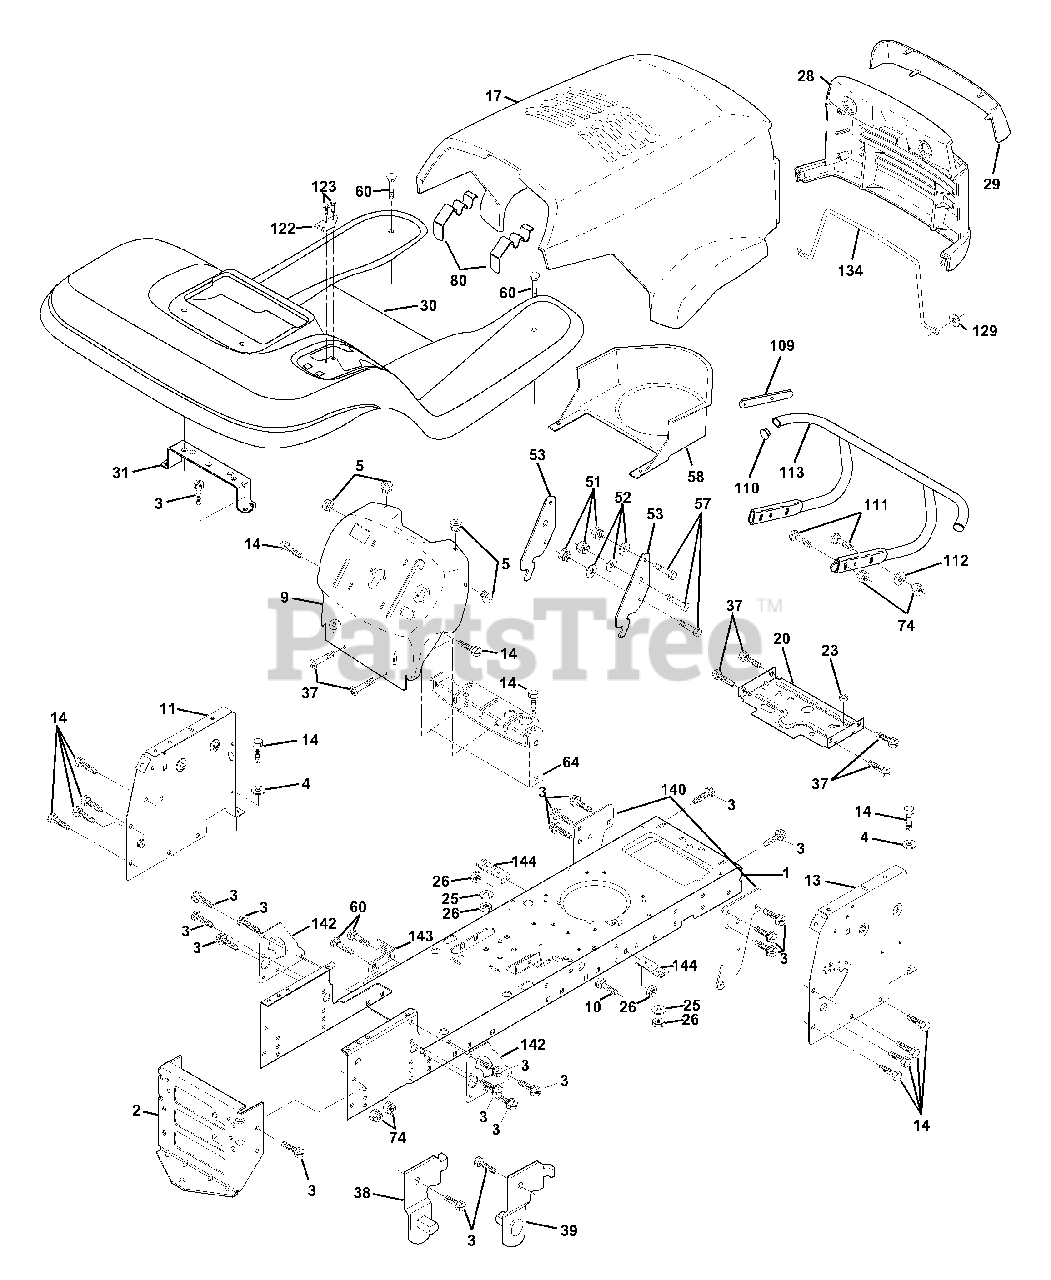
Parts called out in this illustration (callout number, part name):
1	Chassis Weldment
2	Drawbar, Stretch
3	Screw Thdrol 3/8-16x3/4 Ty-tt
4	Washer 13/32 x 3/4 x 16 Ga.
5	Bumper Hood/Dash
9	Dash Slkscr PLM E AHM NC Sym
10	Bolt Carriage 3/8-16 x 1
11	Panel Dash Lh
13	Panel Dash Rh
14	Screw Thdrol 3/8-16x1/2 Ty-tt
17	Hood LT/PL Husqvarna
20	Plate Mtg Battery Fuel Tank Fr
25	Washer 13/32 X 13/16 X 12 Ga
26	Nut Lock Hex W/Ins 3/8-16 Unc
28	Grille LT/PL Husqvarna
29	Lens LT/PL Husqvarna
30	Fender Footrest STLT Pnt
31	Bracket Support Fender
37	Screw Thdrol 6/16-18 x 1/2 TYT
38	Bracket, Asm. Pivot, L.H., Mower Rear
39	Bracket, Asm. Pivot, R.H., Mower Rear
51	Nut Lock Hex W/Ins 1/4-20
52	Washer 9/32 x 7/8 x 16 Ga.
53	Bracket Pnt. Pick off LT/PL Husqvarna
57	Bolt Hex 1/4-20 x 3/4
58	Air Duct Engine P/L
60	Bolt Rdhd Sqnk 3/8-16unc x 3/4
64	Dash Lower STLT
74	Nut Crownlock 3/8-16 UNC
80	Latch Hood Plm Husqvarna
109	Bracket Extension Bumper
110	Plug Plastic
111	Bolt RDHD 3/8-16 UNC x 1-1/2
112	Washer 13/32 x 13/16 x 16 Ga.
113	Bumper Asm.
129	Washer 9/32 x 5/8 x 16 Ga.
134	Rod Support Hood LT/PL Husq.
140	Bracket Chassis Front 7 Ga.
142	Plate Reinforcement STLT
143	Bracket Swaybar Chassis
144	Bracket Pnt Footrest STLT
146	Screw Torx Hd Thd 5/16-18 UN-2A
